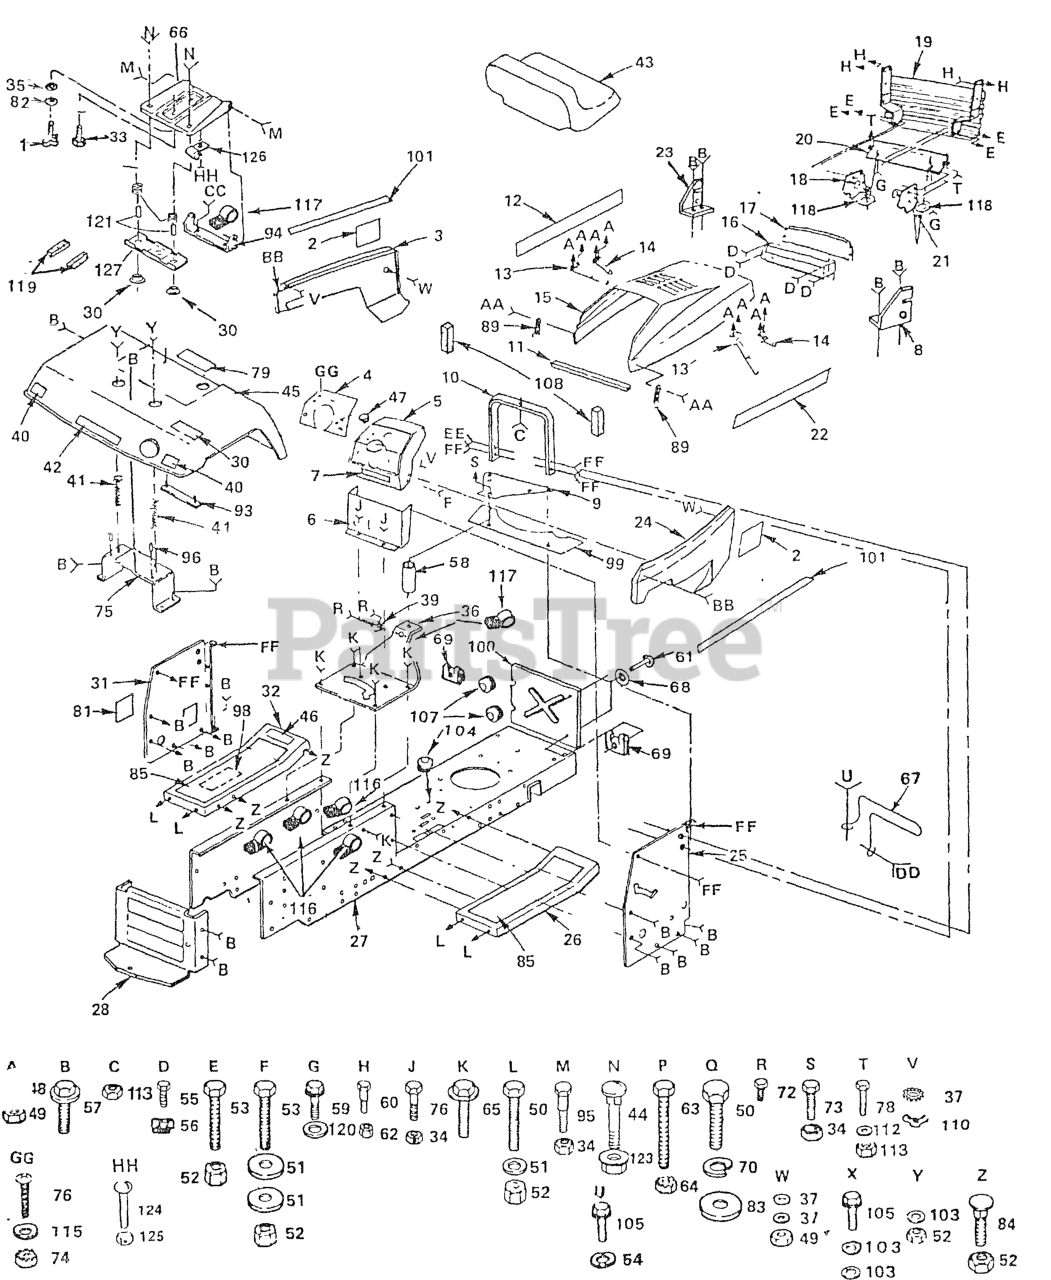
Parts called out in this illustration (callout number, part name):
1	KNOB 1/2" YT
2	DECAL, SIDE PANEL NLA
3	Panel - Side, L.H.
4	PLATE,DASHBOARD
5	DASHBOARD
6	Dash Assembly - Lower
8	SUPPORT RH YTH
9	PLATE SUPPORT T NLA
10	SUPPORT ASS'Y
11	STRIP FORM
13	STRAP ASSY LT
14	STRAP ASSY LT
15	HOOD
16	REPL BY 532 12 43-92
18	SUPPORT LH YTH
19	GRILL
21	BRACKET NLA
23	SUPPORT LH YTH
24	Panel - Side, R.H.
25	PANEL LT NLA
26	FOOTREST RH
27	CHASSIS ASSY NLA
28	DRAWBAR
31	Panel - Dash, L.H.
32	FOOTREST LH**
33	BOLT, SHOULDER**
34	LOCKNUT
35	WASHER
37	LOCKWASHER GT
39	BUSHING LT
40	REFLECTOR-TAIL YT
41	SPRING COMPRESSION
43	SEAT
44	Bolt, Roundhead 1/4 - 20 x 1 1/4
47	PLUG BUTTON T
48	LOCKWASHER
49	NUT.WING.LCK.NYL.NOTCH.1/4-20
51	WASHER
53	BOLT
54	WASHER
55	Screw - Hex Washer Hd. Tapping 10 - 16 x 5/8
57	SCREW
59	SCREW.THDROL.5/16-18X3/4.TTY
60	BOLT T
62	NUT.CROWNLOCK.1/4
65	SCREW LT
66	Pan - Seat
67	PROTECTOR NLA
68	RETAINER LT
69	RECEPTACLE LT
70	WASHER, LOCK 3/8
72	SCREW LT
73	Bolt-Hex 5/16-18 x 2 Gr 2
74	NUT
75	BRACKET-FENDER YT
76	Screw - Mach. 5/16-18 x 3/4
78	SCREW
81	COVER ACCESS
82	Washer- 17/32 x 1-1/16 x 20 Ga.
83	WASHER T
84	Bolt - Carriage 3/8 - 16 x 3/4
85	STRIP FORM
89	LATCH.HOOD.
93	STRAP-FENDER YT
94	BRKT,SEAT PIVOT**
95	NUT-PUSH YT
96	BOLT, SHOULDER LT
100	SHIELD HEAT HYT
100	NUT.WING.LCK.NYL.NOTCH.1/4-20
101	DECAL SIDE STRIPE
103	WASHER
104	SNAP BUSHING T
105	SCREW GTV
106	LOCKWASHER
107	SNAP BUSHING T
108	STRIP FORM
109	Lock Washer 1/4 Int. Ext.
112	WASHER PM
113	NUT
115	WASHER
116	INSUL CLIP T
117	CLIP
119	STRIP FORM
120	WASHER M
121	SPACER SPLIT
123	NUT T
125	Nut -Keps,#10-32UNF
126	CLIP T
127	BRKT SWITCH
